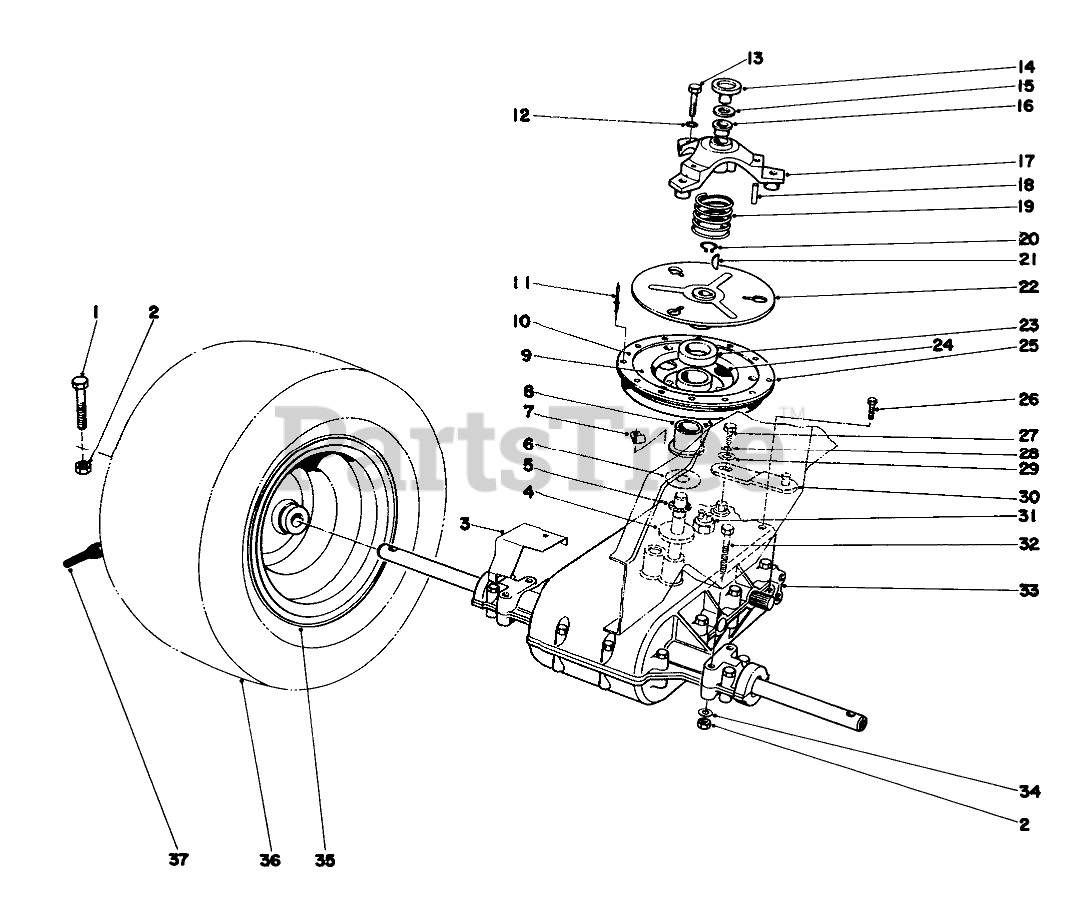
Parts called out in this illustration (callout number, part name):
1	SCREW-HH
2	NUT-LOCK, CONE
3	GRASS SHIELD B
4	THRUST WASHER
5	NEEDLE BRG
6	THRUST WASHER
7	CLIP-FUEL LINE
8	Bushing
9	Retainer Ring
10	CLUTCH PAD
11	Rivet
12	WASHER-LOCK
13	SCREW-HH
14	CLUTCH CAP
15	THRUST RACE
16	BUSHING-FLANGE
17	Cover Assembly (Incl. Ref. #16 & 18)
18	NEEDLE BRG
19	COMPRESSION SPRING
20	RING-SNAP, EXTERNAL
21	KEY-WOODRUFF
22	Clutch Plate
23	WASHER FELT
25	Sheave Assembly (Incl. Ref. #8, 9-11)
26	SCREW-HWHTF
27	SCREW-HH
28	WASHER-LOCK
29	WASHER-FLAT
30	SHIFT LEVER WA B
31	NEUTRAL SWITCH
32	SCREW-HH
33	Transaxle
34	WASHER-PLAIN
36	Tire
37	STEM-VALVE
